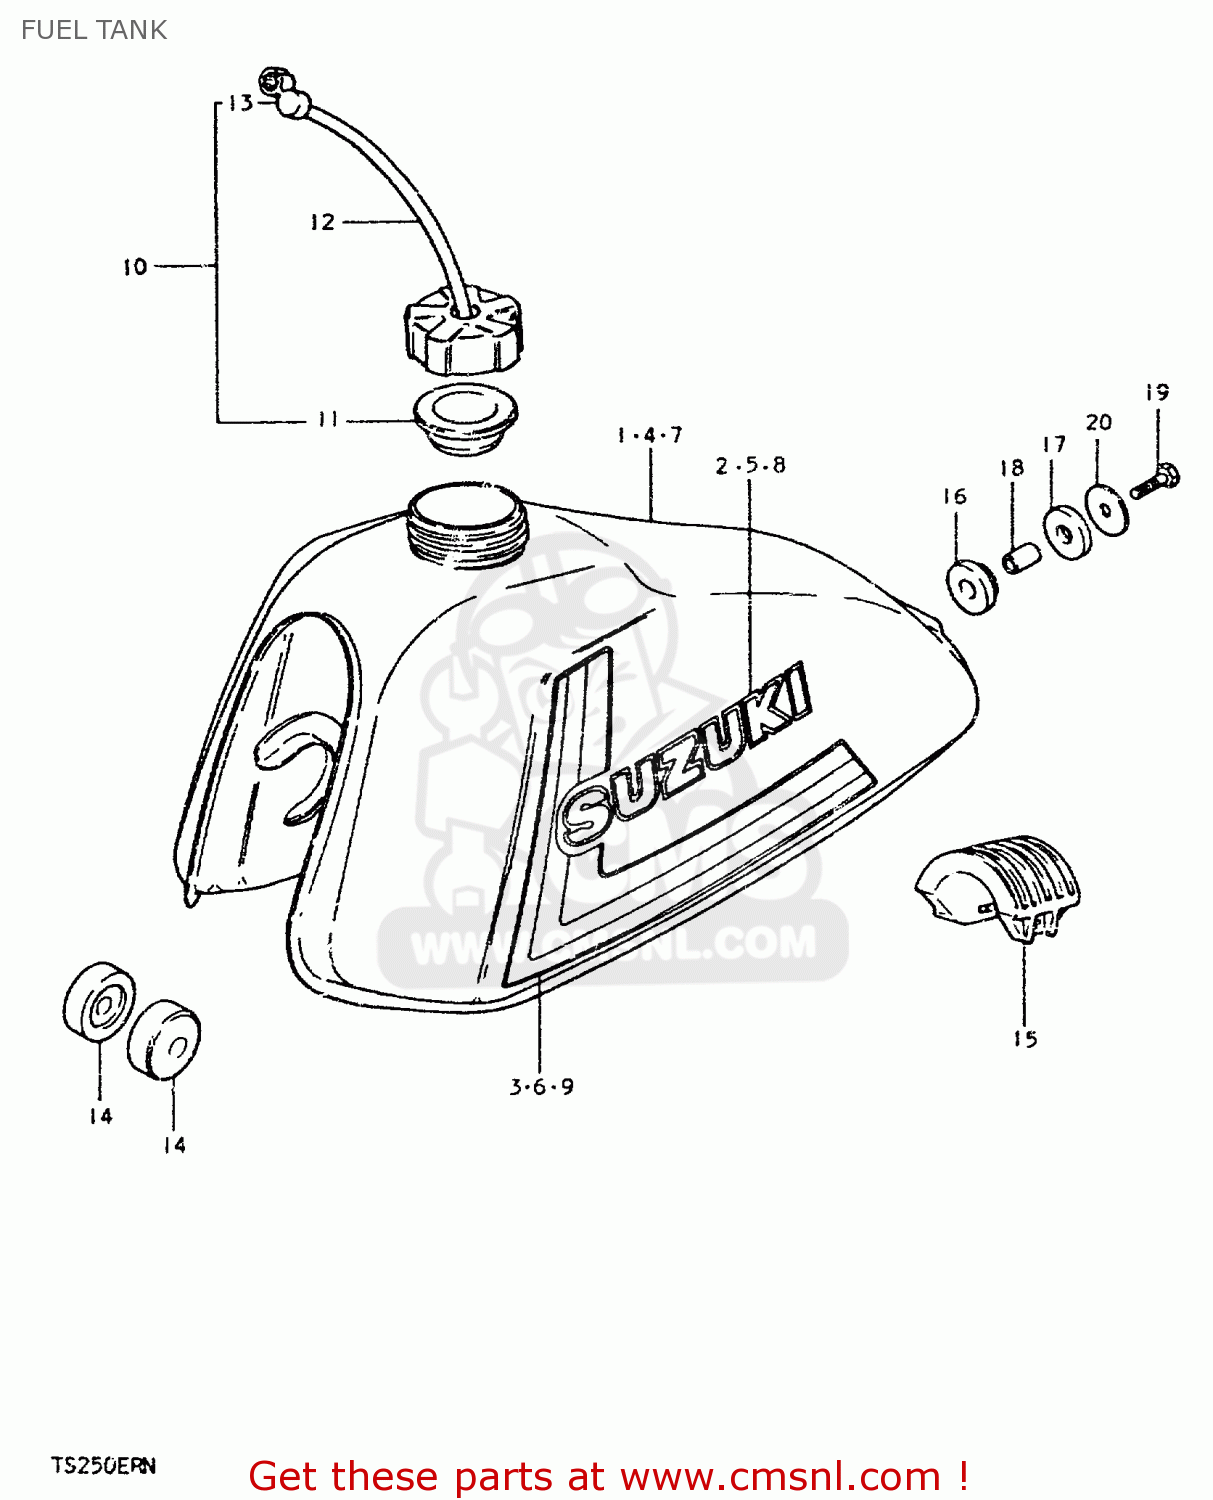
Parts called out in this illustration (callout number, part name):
1	TANK, FUEL
2	EMBLEM
3	TAPE SET
4	TANK, FUEL
5	EMBLEM(BLACK)
6	TAPE SET
7	TANK, FUEL
8	EMBLEM(BLACK)
9	TAPE SET
10	CAP SET,FUEL TANK
11	GASKET,FUEL TANK CAP (NAS)
12	HOSE
13	CLAMP,FUEL TANK BREATHER HOSE
14	CUSHION
15	CUSHION,FUEL TANK
16	CUSHION
17	CUSHION
18	SPACER (8.2X12X17)
19	BOLT (8X30)
20	WASHER (8.5X29X1.6)
